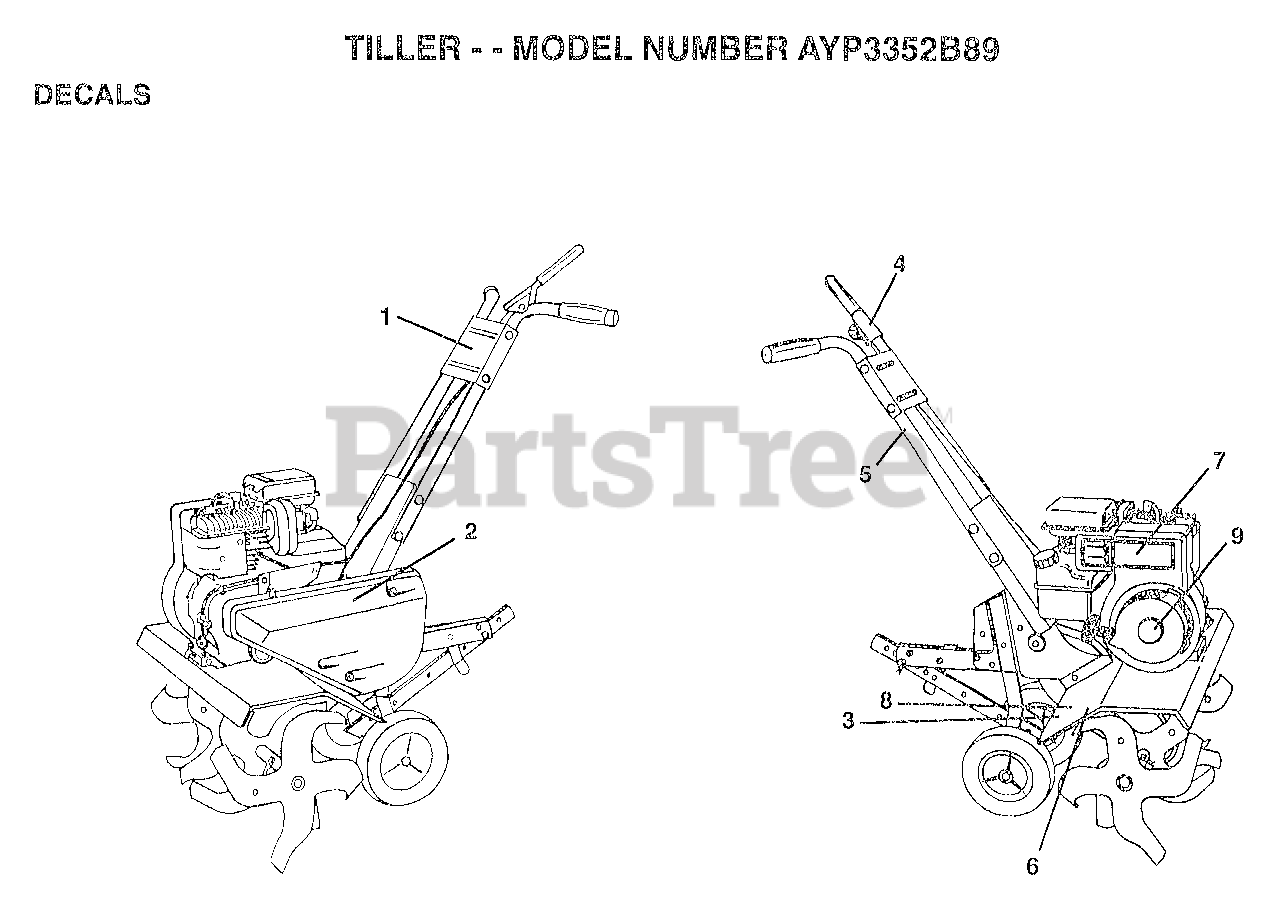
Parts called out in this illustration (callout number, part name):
1	DECAL.CNTRL.PNL.5
2	DECAL.LOGO
4	DECAL TI
5	DECAL TI
6	DECAL.TINE.SHIELD
7	DECAL, BRIGGS & STRATTON
8	DECAL TI
